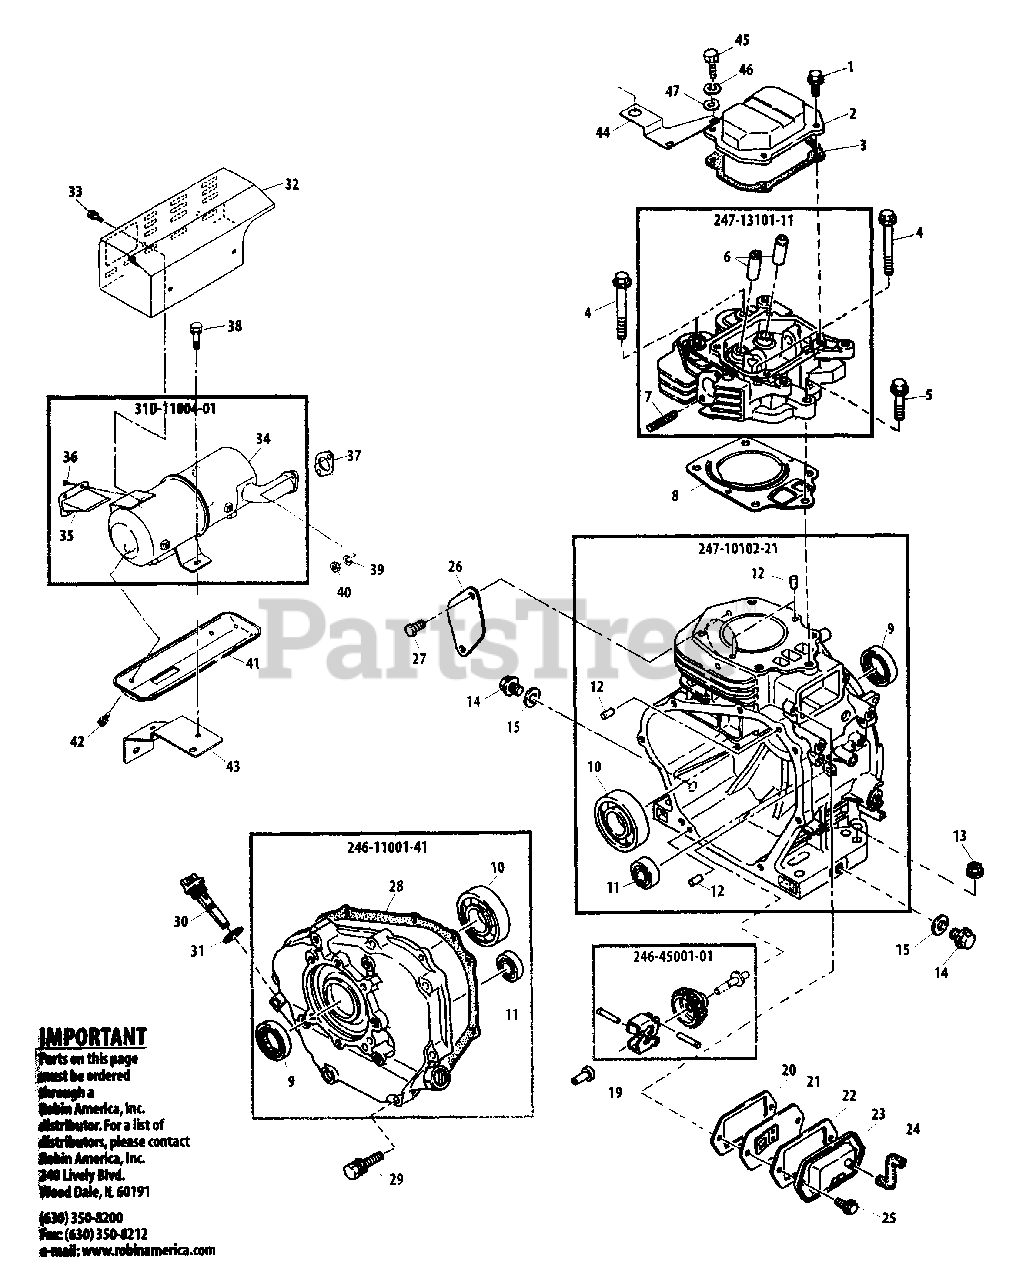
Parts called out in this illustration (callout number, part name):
1	BOLT
2	COVER, ROCKER
3	GASKET
4	BOLT
5	BOLT
6	GUIDE, VALVE
7	STUD
8	GASKET, HEAD
9	SEAL, OIL
10	BEARING, BALL
11	BEARING, BALL
12	PIN - LOCATING
13	NUT - FLANGE
14	PLUG
15	GASKET
19	GOVERNER SLEEVE
20	GASKET
21	PLATE
22	GASKET
23	COVER, BREATHER
24	TUBE
25	BOLT - FLANGE
26	COVER
27	BOLT
28	GASKET
29	BOLT
30	GAUGE, OIL
31	GASKET
31D-11004-01	MUFFLER ASSY
32	COVER, MUFFLER - UPPER
35	SCREEN, SPARK ARRESTOR
38	BOLT - 8X20
39	LOCKWASHER - 8
41	COVER, MUFFLER - LOWER
44	STOPPER STAY
46	LOCKWASHER - 10
246-11001-41	MAIN BEARING COVER ASSY
246-45001-01	GOVERNOR GEAR ASSY
247-10102-21	CRANKCASE ASSY
247-13101-11	CYLINDER HEAD ASSY
